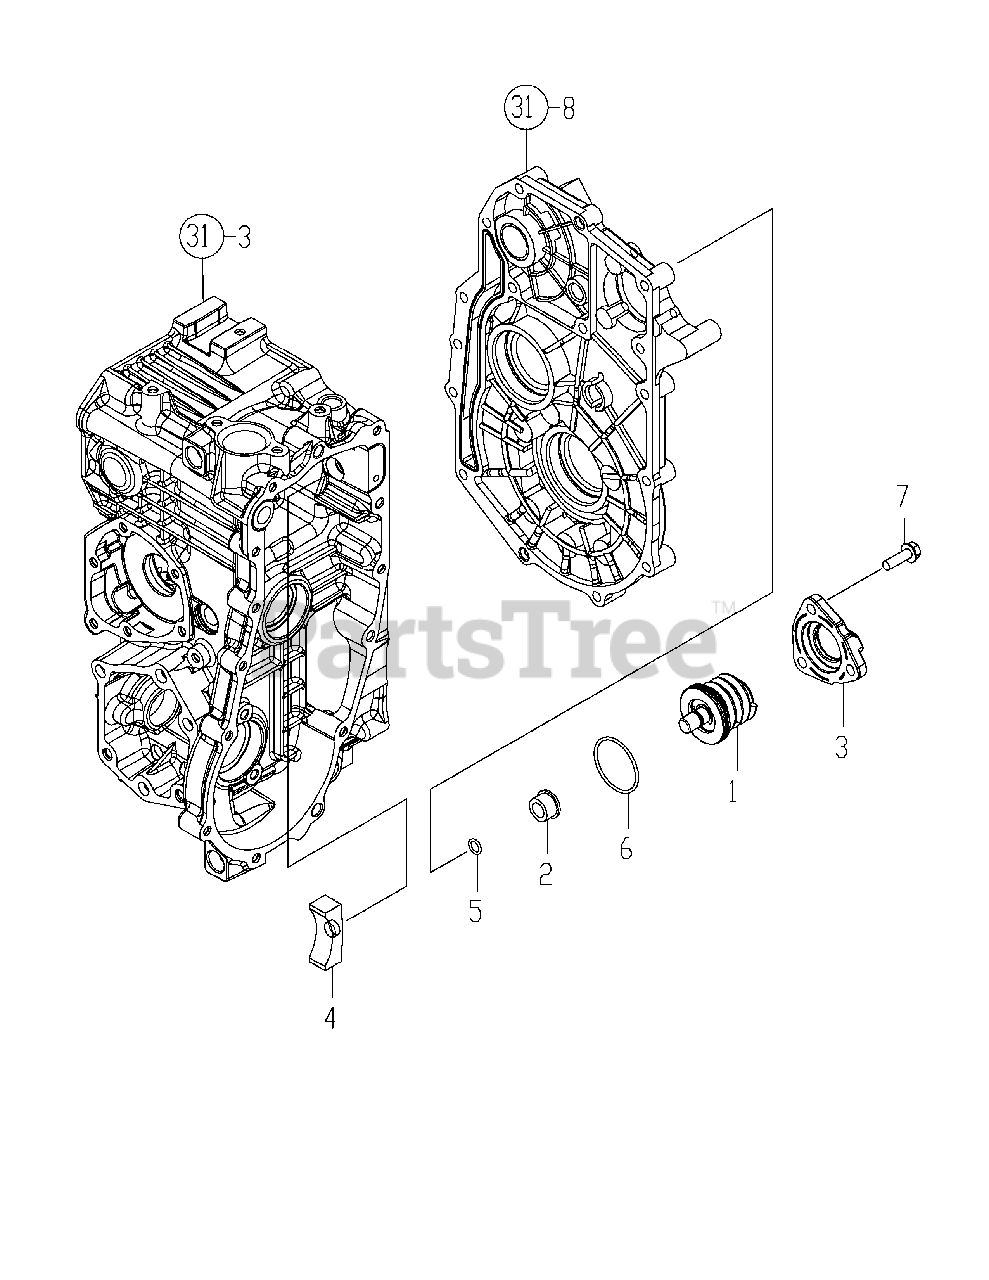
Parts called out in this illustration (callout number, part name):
1	BRAKE KIT, PTO
2	COLLAR, BRAKE PIN
3	COVER, PTO BRAKE
4	SHOE, PTO BRAKE
5	PACKING, P 10.0
6	PACKING, 2045
